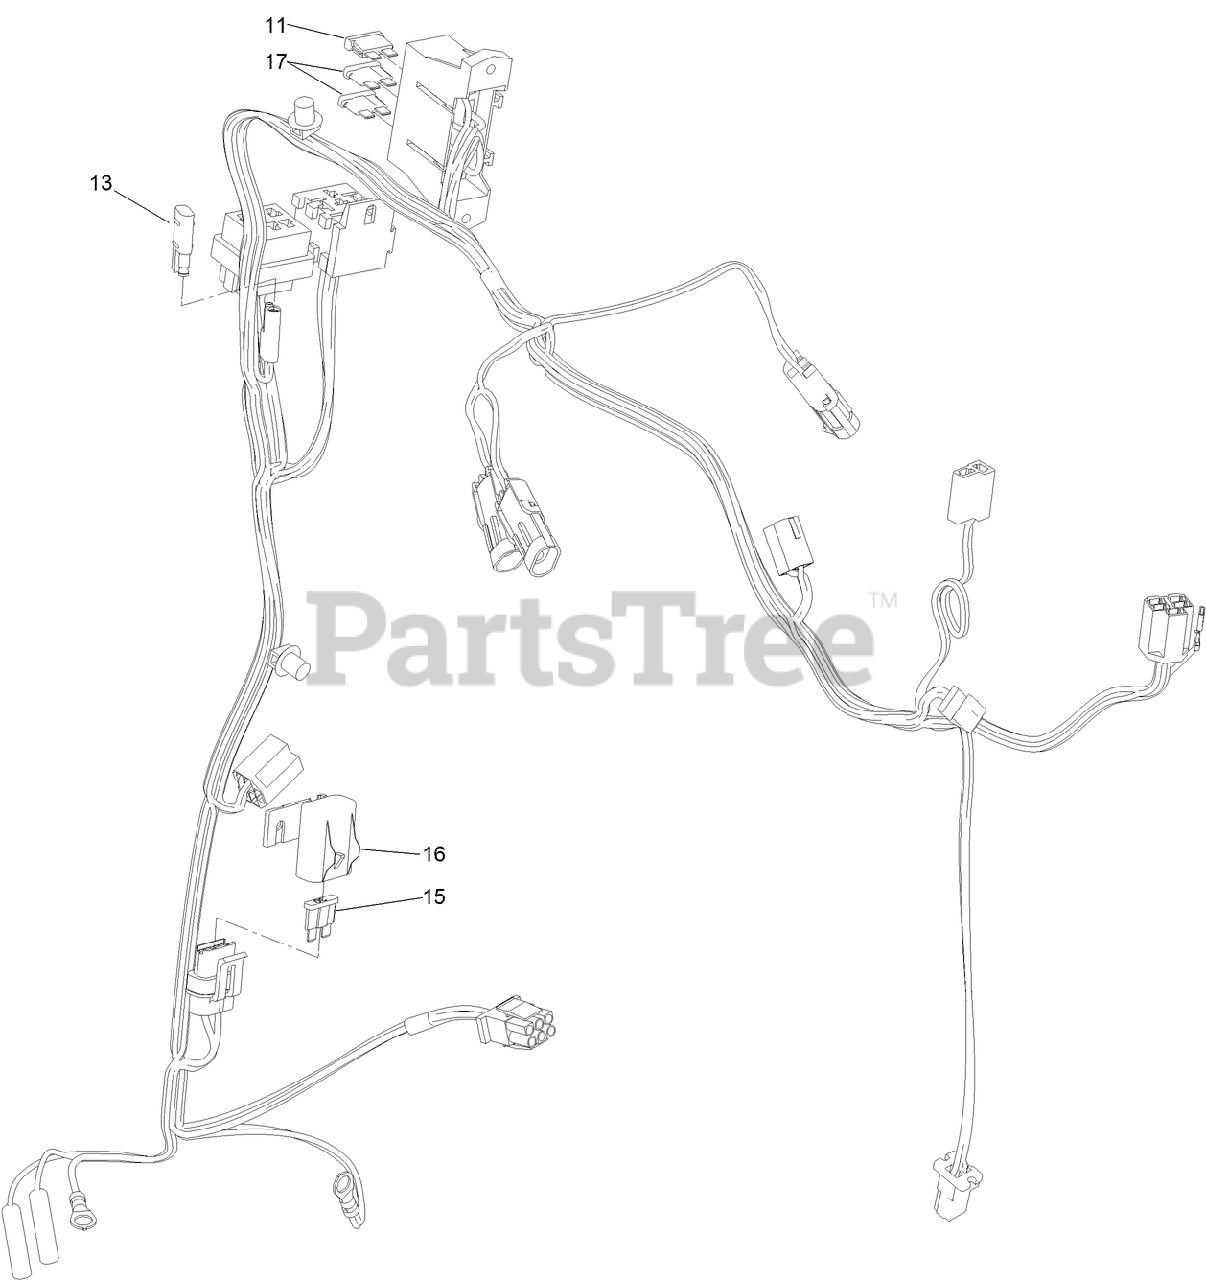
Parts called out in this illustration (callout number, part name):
11	FUSE-BLADE, 15 AMP
13	CAP-PLUG
15	FUSE-BLADE, 30 AMP
16	COVER-FUSE, SINGLE
17	FUSE-BLADE, 10 AMP
